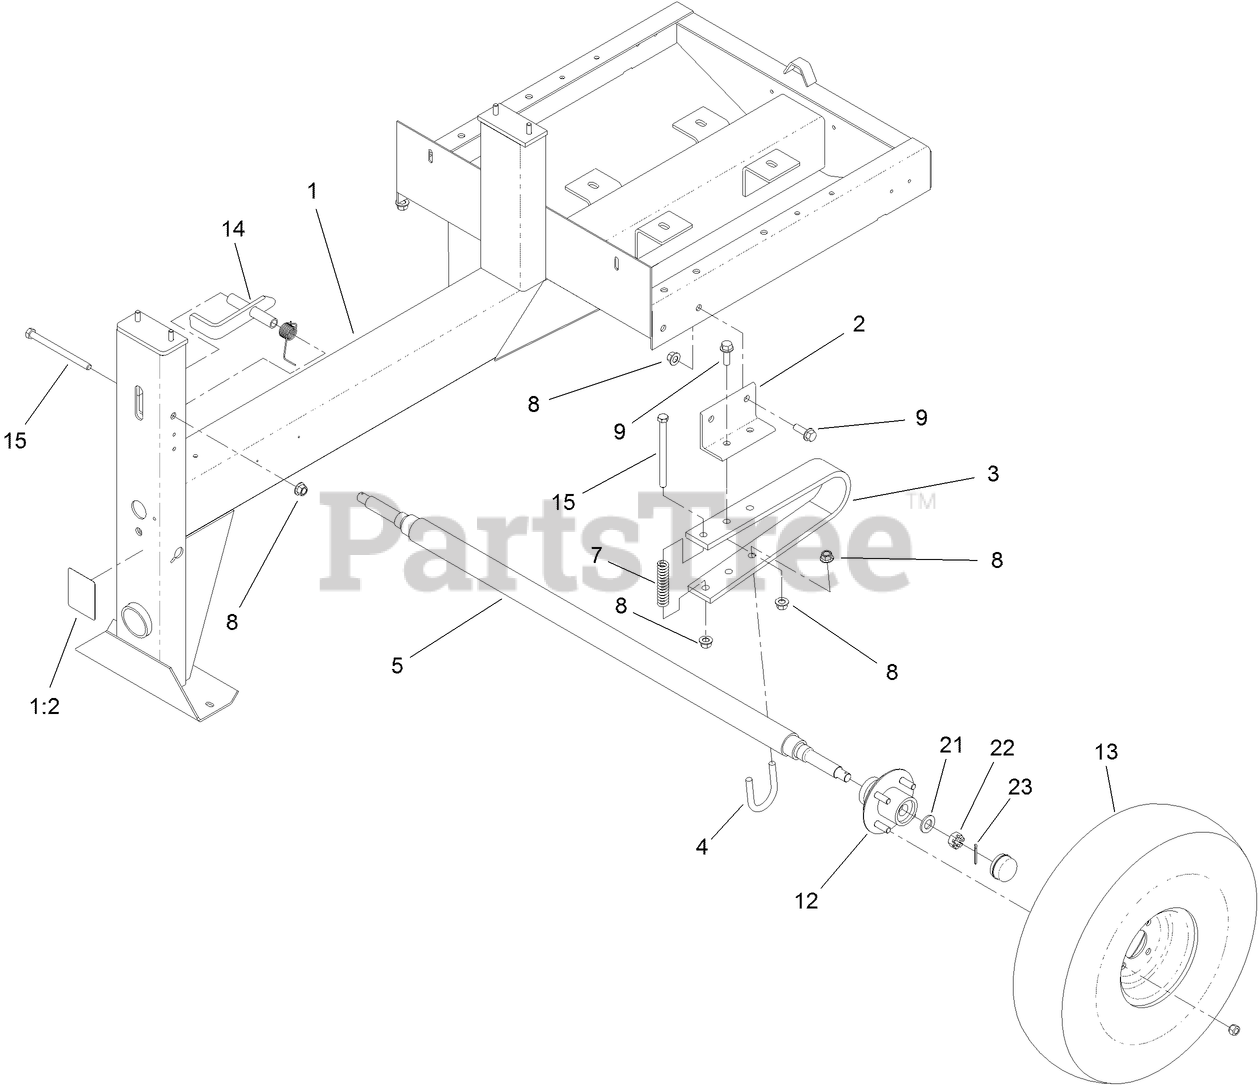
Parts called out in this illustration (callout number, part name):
1	FRAME ASM
1:2	DECAL-SAFETY CHAIN, TOWING
2	BRACKET-AXLE, SPRING
3	SPRING-LEAF
4	BOLT-U
5	AXLE-SPRING
7	SPRING-COIL
8	NUT-LOCK
9	SCREW-HHF
12	HUB ASM
13	TIRE AND RIM ASM
14	LATCH-DRUM
15	SCREW-HH
21	WASHER-FLAT
23	PIN-COTTER
